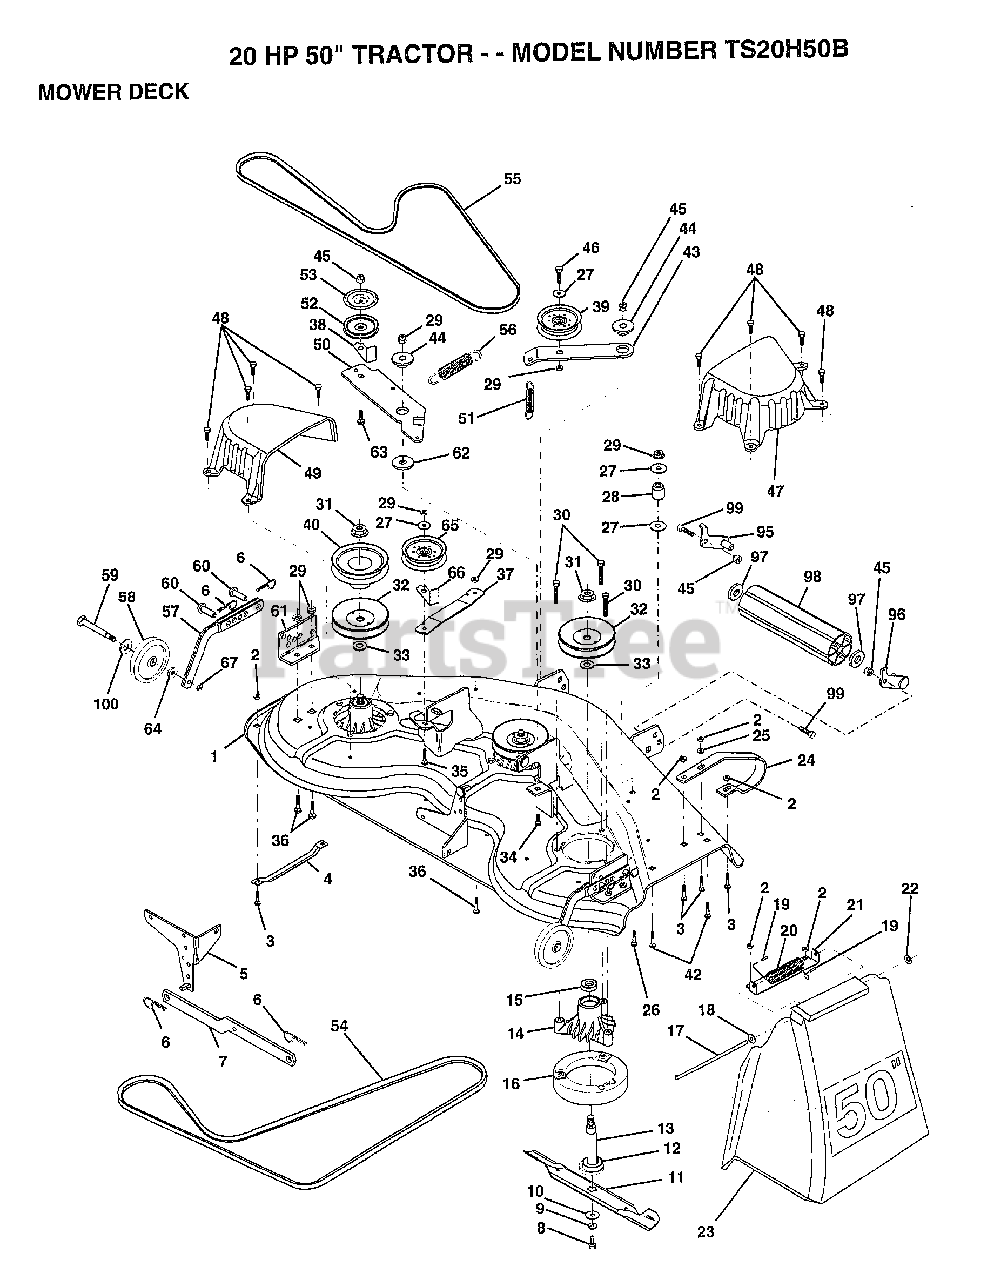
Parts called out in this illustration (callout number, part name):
1	DECK ASM MWR 50VT
2	NUT
4	RUNNER-LH M
5	BRKT.ASM.SW.44/50
8	BLADE BOLT
10	WASHER.HARD.BLADE
11	"BLADE.50"" HD"
12	BEARING.BALL
13	SHAFT.ASM.W/BRNG
14	HOUSING.MAND.44.V
15	BEARING
16	STRIPPER RND MWR
17	ROD-HINGE T
18	WASHER
19	CAP-SLEEVE LT
20	SPRING TORSION
21	BRKT DEFLECTOR
22	NUT PUSH M
23	DEFLECTOR
24	"RUNNER RH 50"" DK"
25	WASHER M
26	BOLT
27	WASHER
29	NUT
33	WASHER
34	BOLT.3/8-14X1.25
35	BOLT
36	BOLT D
37	STIFFENER.ARM.IDL
39	FLAT IDLER PULLEY
40	"PULLEY.DRIVEN.44"""
42	BOLT
43	"ARM.IDLER.SEC.44"""
44	SPACER RETAINER
47	"COVER.MAND.RH.44"""
48	SCREW.1/4-20X5/8
49	COVER.MANDREL.LH
50	ARM.IDLER.PRIMARY
51	"SPRING.SEC.44""VEN"
52	PULLEY.IDLER.VGRO
53	SHIELD.IDLER.44.V
54	BELT V PRIM 50
55	BELT.V.GDRIVE.95
56	SPRING.EXT.DECK.
57	BAR.ASM.GUAGE.WHL
58	WHEEL.GAGE.BLK.PL
59	BOLT M
60	PIN.CLEVIS
61	BRACKET.GUAGE.WHL
62	HARDENED WASHER
63	BOLT.3/8-16X1.50
64	WASHER
65	IDLER-FLAT T
67	LOCKNUT
97	WASHER
99	BOLT
100	WASHER
